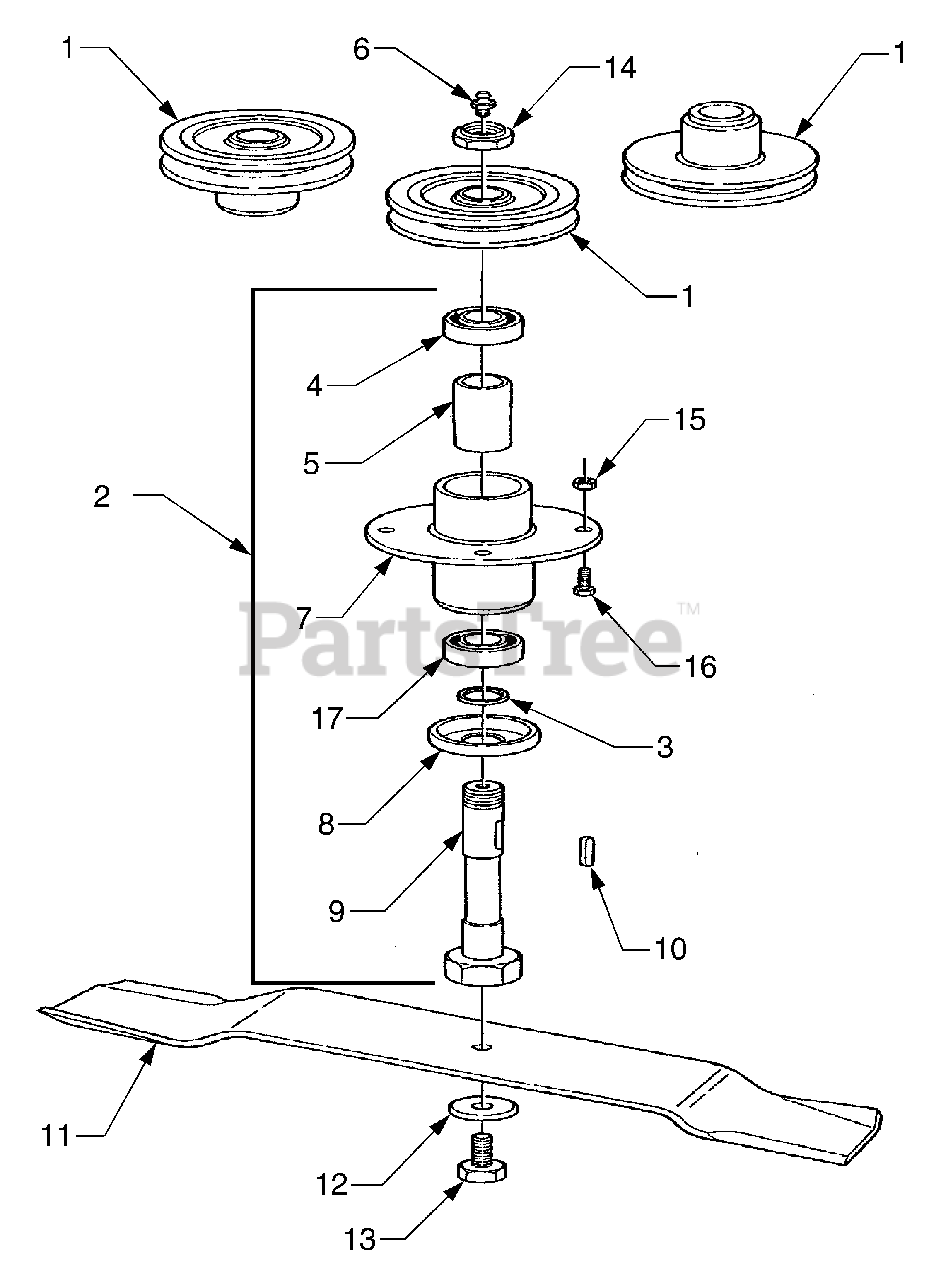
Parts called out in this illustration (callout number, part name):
2	Spindle Assembly
3	Spacer Washer
6	Grease Fitting
9	Blade Shaft
11	Blade - Standard Lift
12	Spring Washer
16	Bolt, 10 x 30
18	Spindle Assembly - Complete
